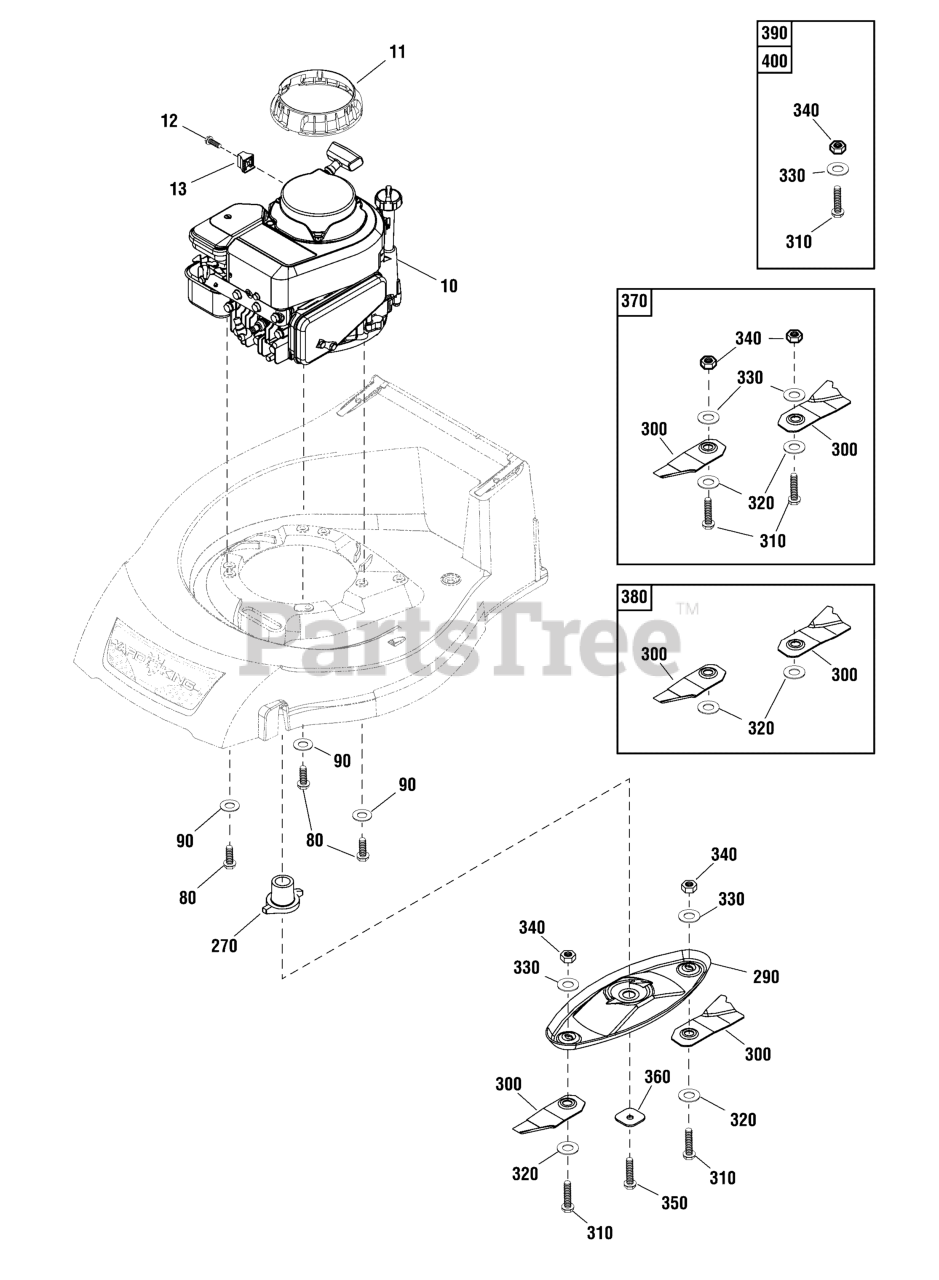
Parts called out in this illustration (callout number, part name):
10	** Engine, Briggs & Stratton 450 Series
11	FINGER GUARD, 450 Series, Black
13	SPACER, Throttle Mount
80	BOLT, Taptite, HW, 3/8UNC x 30
90	WASHER, Engine Mounting
270	SLEEVE, Locking, 4 Stroke
290	BLADE DISC, Oval
300	BLADE
310	BOLT, Blade
320	WASHER, Blade Tension
330	WASHER, Belleville, Blued
340	NUT, Nylock, 3/8 UNC
350	BOLT, Blade Disc
360	WASHER, Blade Disc
370	KIT, Blade & Bolt, Bulk Pack (1 Pack)
380	KIT, Blade & Bolt, Bulk Pack (40 Pairs)
390	KIT, Hardware, Bolt, Washer, Nut (1 Pack)
400	KIT, Hardware, Blade Mounting , Bulk Pack (50 Pairs)
